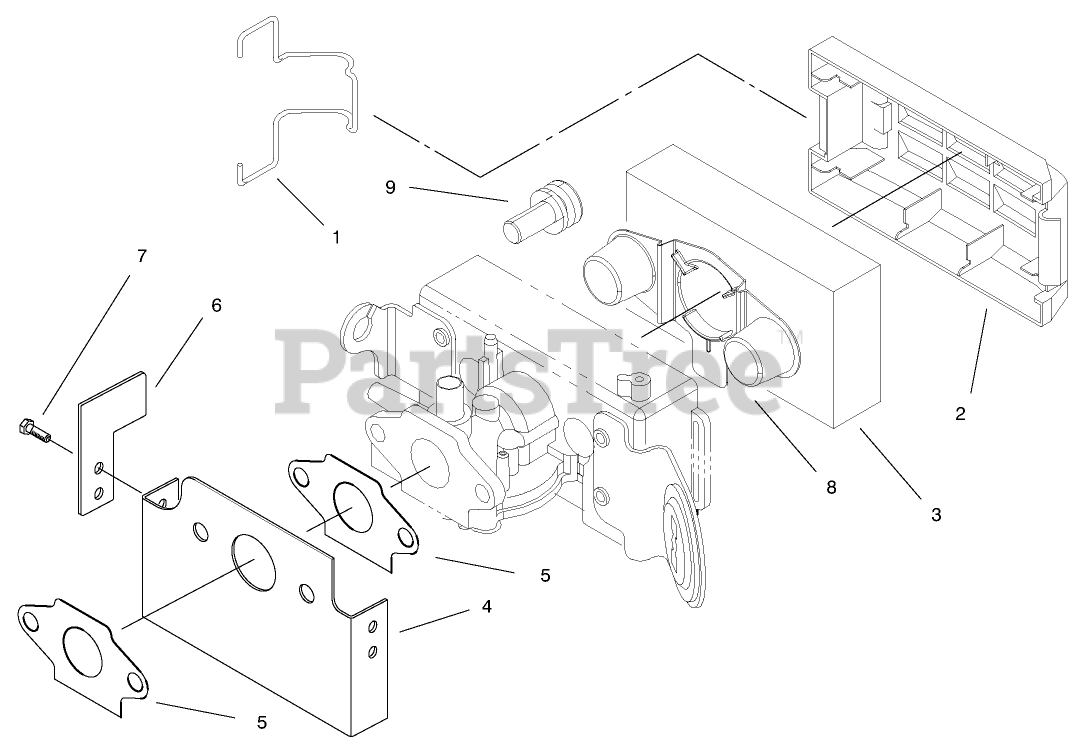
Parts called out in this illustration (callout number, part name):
1	RETAINER-COVER, FILTER
2	COVER-AIR FIL. V
3	ELEMENT-AIR FIL VF
4	SHIELD-CARB V INTL
5	GASKET-CARB VF
6	SHIELD - GOV. F (INTL)
7	SCREW V
8	SHIELD-FUEL V
9	SCREW
